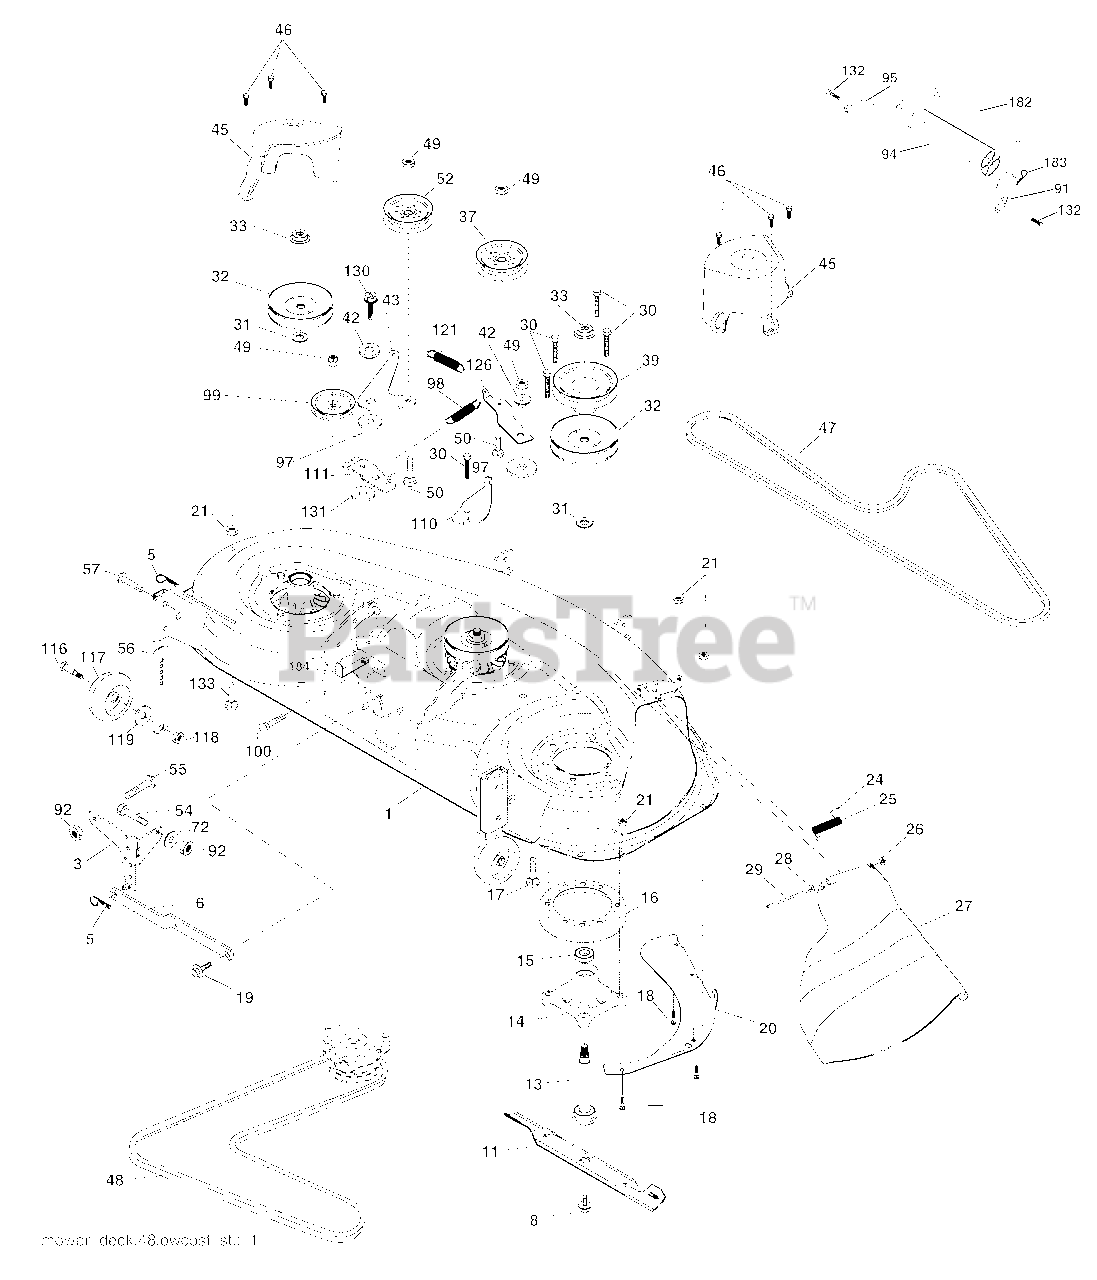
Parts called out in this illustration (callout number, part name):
1	Deck Weldment Mower 48
3	Bracket Asm., Sway Bar
5	Retainer Spring
6	Bar Sway Deck
8	Bolt, 7/16 Asm. Blade
13	Shaft Asm. Mandrel Sealed
14	Housing Mandrel 48"
15	Bearing, Ball, Mandrel
16	Stripper, Mower
17	Bolt Rdhd Sq Neck 3/8-16 x 1.25
18	Bolt, Carriage 5/16-18 x 5/8
19	Bolt, Hex Head, Shoulder 5/16-18
20	Baffle, Vortex Mower
21	Nut, Crownlock 5/16-18 unc
24	Cap, Sleeve
25	Spring, Torsion
27	Shield, Deflector Mower
28	Washer 11/32 x 5/8 x 16 Ga.
29	Rod, Hinge
30	Screw, Thdroll, Washer Head
31	Washer, Spacer Mower Vented
32	Pulley, Mandrel
33	Nut, Flg. Top Lock Cntr. 9/16
37	Pulley, Idler, Flat
39	Pulley, Idler, Driven
42	Spacer, Retainer
43	Arm, Idler Secondary
45	Cover, Mandrel Deck
46	Screw, Thdroll. 1/4-20 x 5/8
47	V-Belt, Mower, Secondary
48	V-Belt, Mower, Primary
49	Nut, Lock 3/8-16 unc
50	Bolt, Carriage 3/8-16 x 1-1/2 Gr. 5
52	Pulley Idler Flat 46 Pri. Drive
54	Bolt Fin Hex 3/8-16 x 1
55	Bolt Rdhd Sqnk 3/8-16 x 1
56	Bar Pnt Adjusting Wheel Gauge
57	Pin Head Rivet
72	Washer 13/32 x 13/16 x 12
91	Bracket, Asm Noseroller, RH 48
92	Nut Lock Hex w/Ins 3/8-16
94	Roller, Nose 48"
95	Bracket, Asm Noseroller LH 48
97	Washer Hardened
98	Spring Primary Drive
99	Pulley Idler "V"
100	Bolt RDHD Sqnk 3/8-16 unc x 2
110	Arm Spring Secondary
111	Arm Spring Fixed Tension
116	Bolt, Shoulder
117	Gauge Wheel
118	Nut, Centerlock 3/8-16 unc
119	Washer 3/8 x 7/8 x 14 Ga.
121	Spring Secondary Drive
126	Arm, Idler, Primary Deck
130	Screw 3/8-16 x 1.0
131	Washer 13/32 x 1 x 6 Ga.
132	Screw 3/8-16 x 3/4
133	Bolt Rdhd Sqnk 5/16-18 unc x 3/4
182	Rod Roller Nose
183	Retainer Spring
184	Keeper Belt Idler
